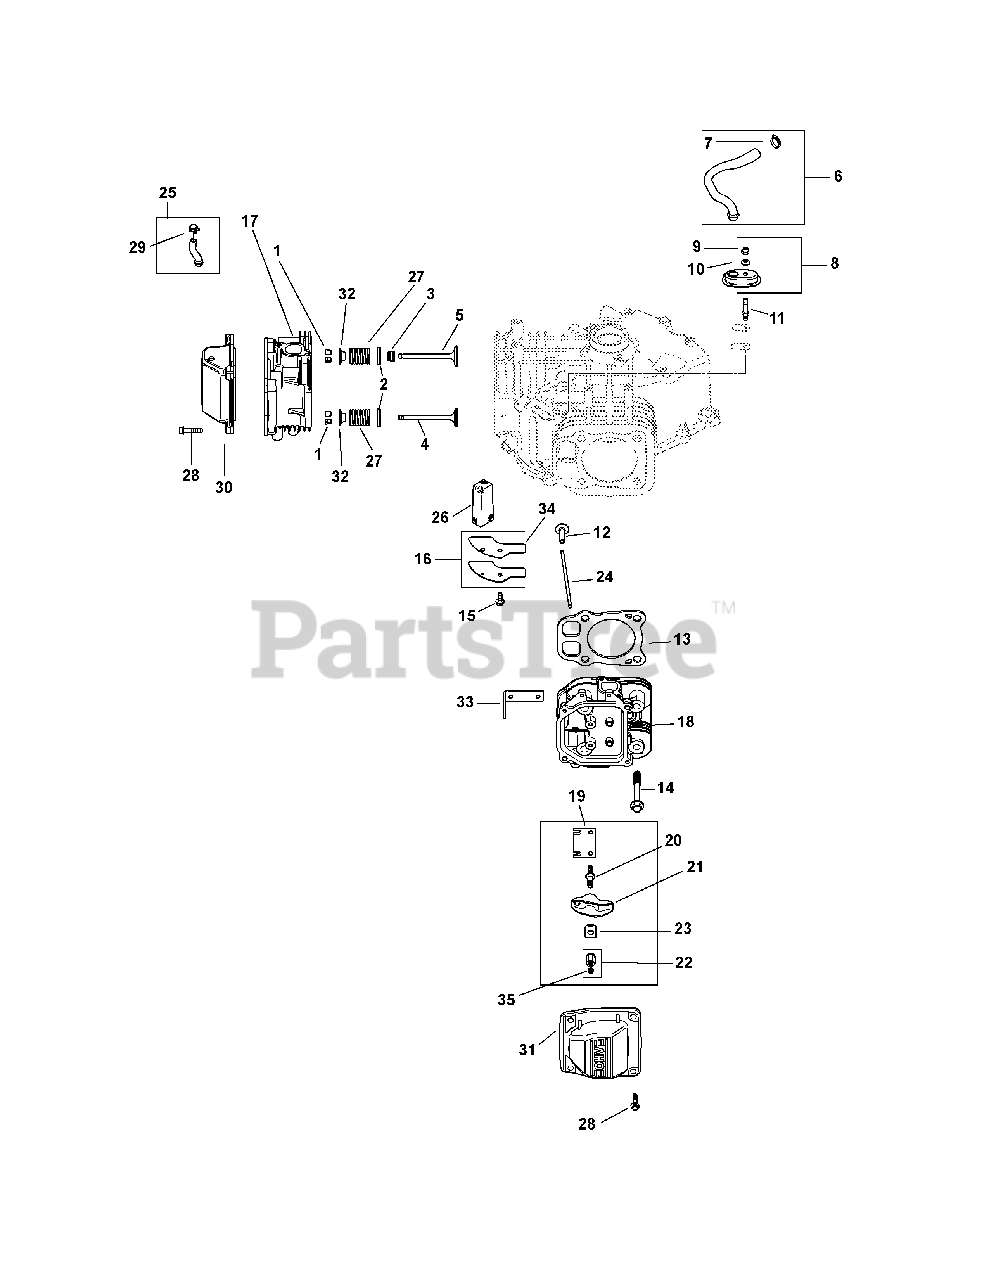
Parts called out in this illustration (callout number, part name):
1	Retainer Kit
2	Spring Retainer
3	Valve Stem Seal
4	Exhaust Valve (STD)
5	Intake Valve (STD)
6	Breather Hose Kit (Inc. #7)
7	Hose Clamp, 1/2
8	Breather Housing Kit (Inc. #9 & 10)
9	Lock Nut, M5 x .8
10	Sealing Washer
11	Breather Cover Stud
13	Cylinder Head Gasket Kit
14	Flange Screw, M10 x 1.5 x 90
15	Flange Screw, M6 x 1.0 x 16
16	Breather Cover Kit
17	#1 Cylinder Head Assembly Kit
18	#2 Cylinder Head Assembly Kit
22	Hex Nut Assembly
23	Rocker Arm Pivot
25	Fuel Pump Hose w/ Clamp Kit
26	Breather Filter
27	Valve Spring
28	Pan Head Screw
30	Rocker Stamped Steel Cover
31	Rocker Stamped Steel Cover
32	Valve Spring Cap
33	Lifting Strap
34	Breather Cover
NS	Cylinder Head Hardware Kit
